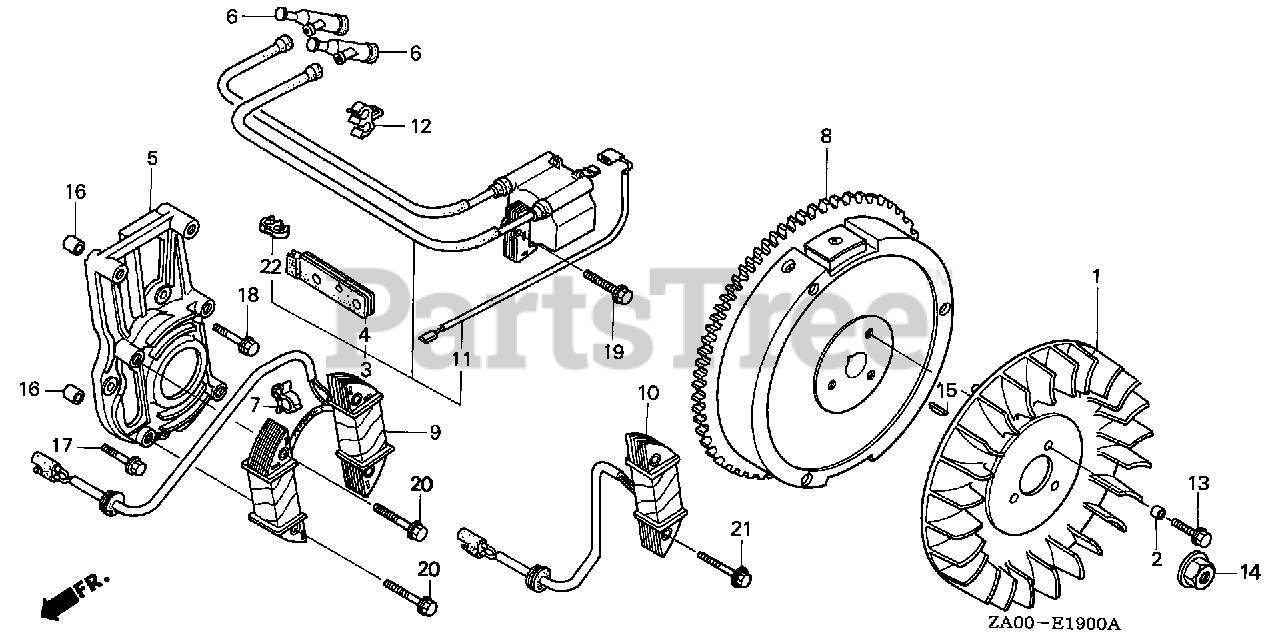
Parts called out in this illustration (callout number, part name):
1	FAN, COOLING
2	COLLAR, FAN
3	COIL ASSY., IGNITION
4	GROMMET, IGNITION WIRE
5	STAY, IGNITION SYSTEM
6	CAP ASSY., NOISE SUPPRESSOR (Honda Code 3526837). (NICHIWA Y-EZ RTFM256)
7	CLIP, IGNITION WIRE (8MM)
8	FLYWHEEL
9	COIL ASSY., CHARGE (10A)
11	WIRE, ENGINE STOP
12	CLIP, RECEIVER PIPE
12	CLIP, IGNITION WIRE
13	BOLT, FLANGE (6X16)
14	NUT, SPECIAL (16MM) (1)
14	NUT, SPECIAL (16MM)
15	KEY, SPECIAL WOODRUFF (25X18)
16	PIN A, DOWEL (8X10)
17	BOLT, FLANGE (6X22)
18	BOLT, FLANGE (6X28)
19	BOLT, FLANGE (6X28)
20	BOLT, FLANGE (6X32)
